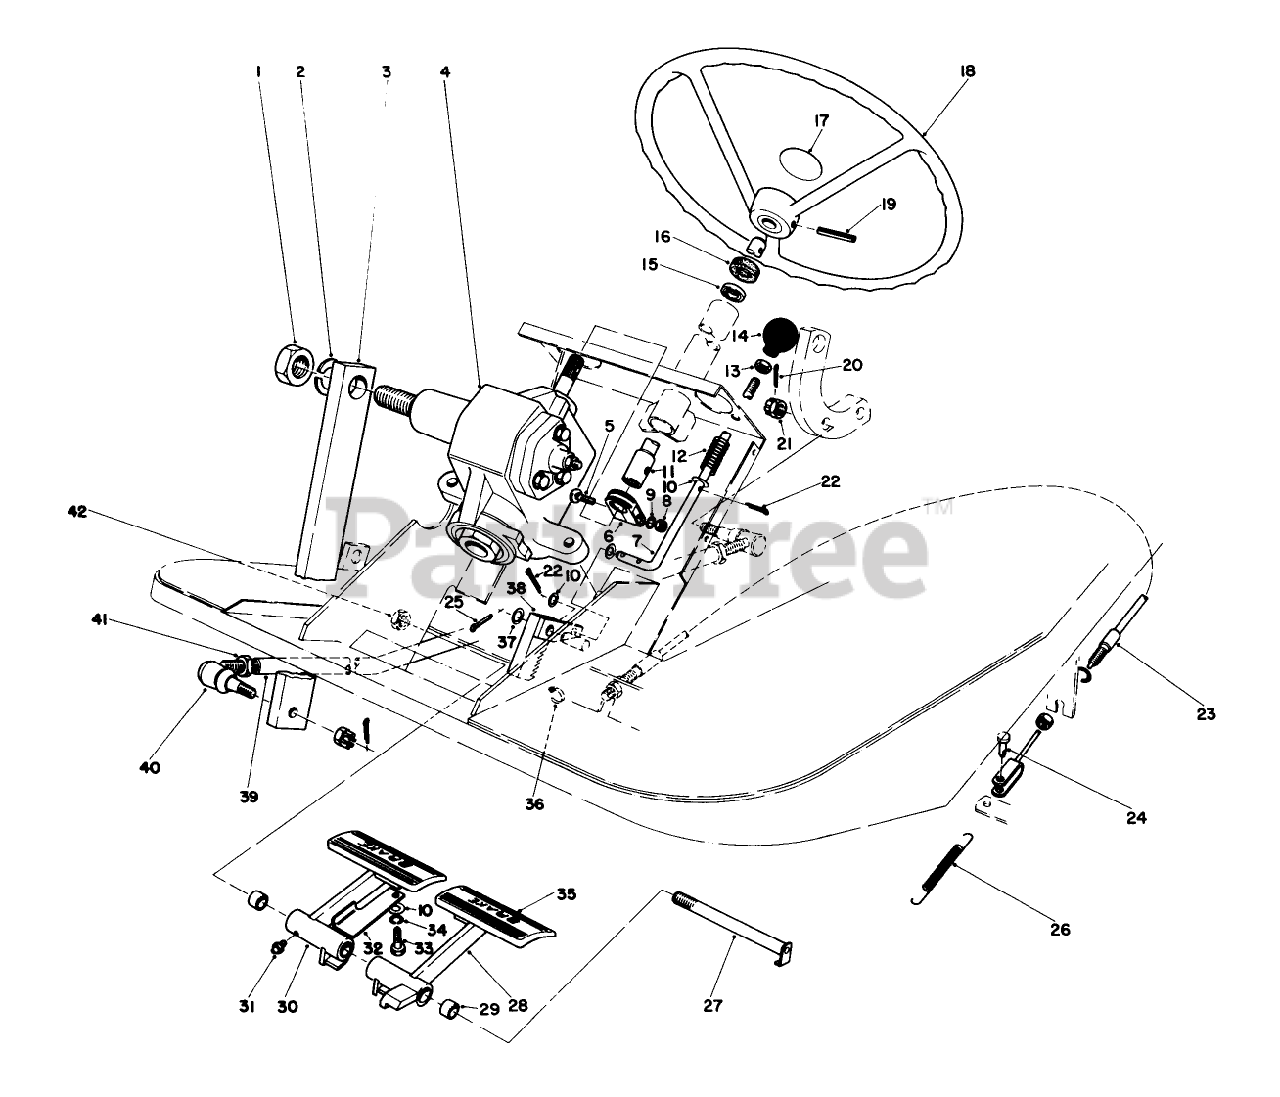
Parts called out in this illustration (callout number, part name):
1	NUT-JAM
2	WASHER-LOCK/SP
3	Pitman Arm
4	Steering Gear
5	7/16-14 X 1-3/4 BOLT
6	STRG COUPLING CLAMP
7	Rod Brake Latch
8	NUT-HEX
9	WASHER-LOCK
10	WASHER-FLAT
11	Shaft-Steering
12	Spring
13	NUT-HEX
15	BALL BRG
16	COVER-DUST
17	STEERING WHEEL CAP
18	STEERING WHEEL
19	PIN-ROLL
20	PIN-COTTER
21	Jam Nut
22	PIN-COTTER
23	RH BRAKE CABLE ASM
24	PIN-CLEVIS
25	PIN-COTTER
26	SPRING-EXTENSION
27	Pin
28	Brake Pedal L.H. (Incl. Ref. #29 & 31)
29	Bushing
30	Brake Pedal R.H. (Incl. Ref. #29 & 31)
31	FITTING-GREASE
32	Latch Parking Brake
33	Capscrew
34	WASHER-LOCK
35	PAD-BRAKE
36	TIE-CABLE
37	WASHER-FLAT
38	Rack
39	FRONT STEERING TUBE B
40	Socket Assembly R.H. (Incl. Ref. #21)
41	NUT-JAM
42	NUT-LOCK, NI
